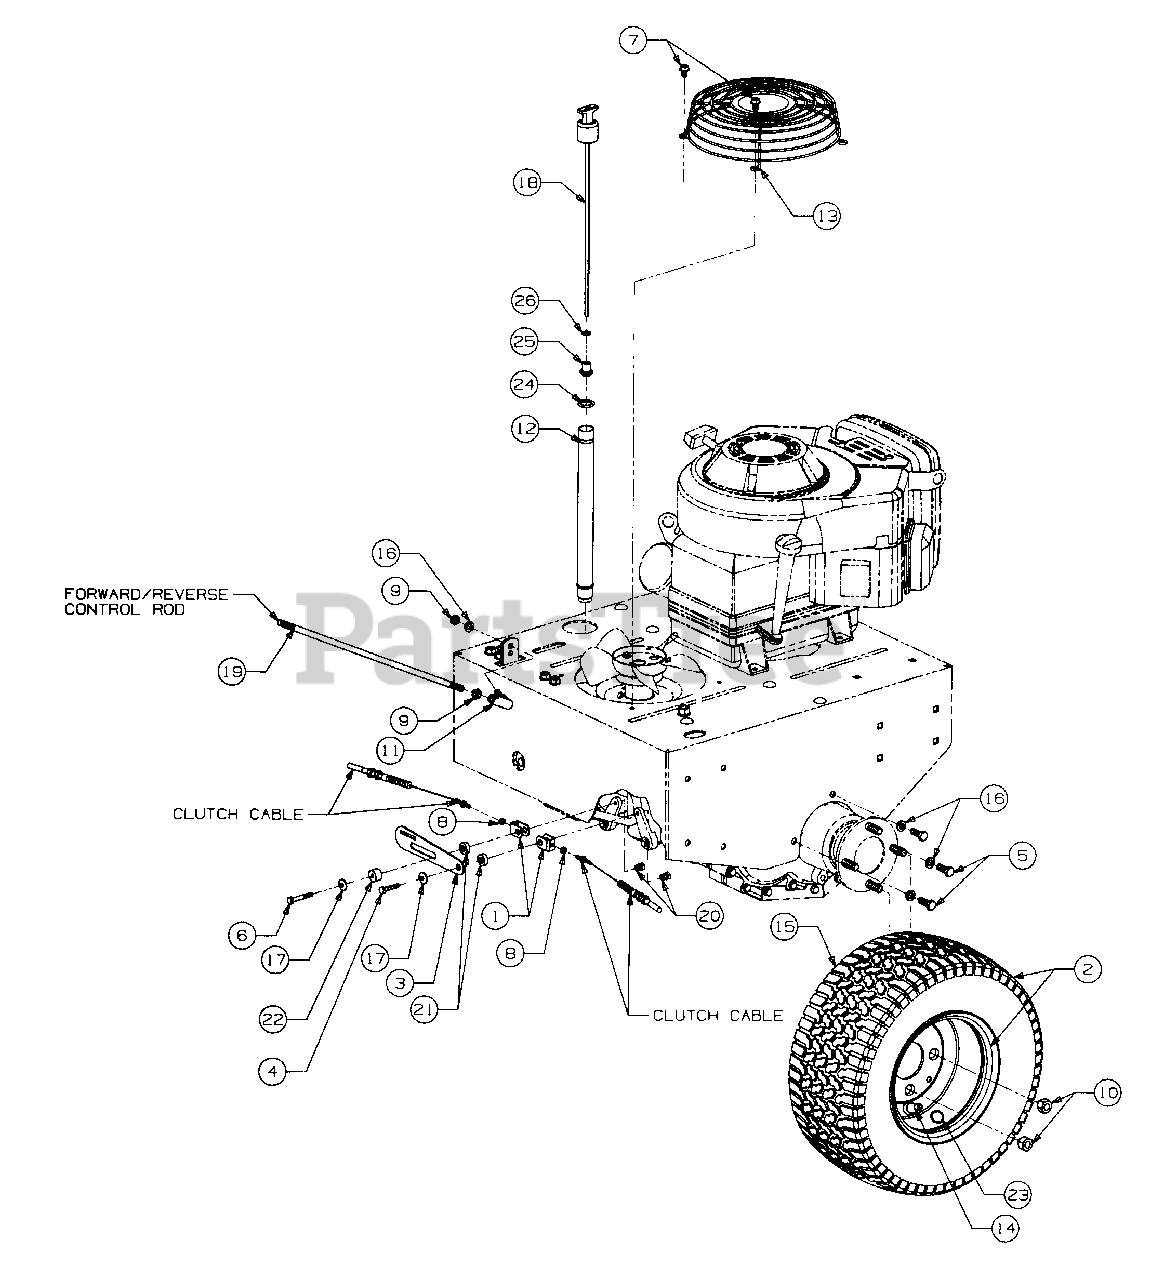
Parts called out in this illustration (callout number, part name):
1	U-Clevis, Clutch Cable
2	Wheel & Tire Assy, Complete, 16 X 7.5-8 (Includes Ref No. 23)
3	Plate, Parking Brake Switch Mount
4	Screw, Hex Cap, 1/4-28 X 1.25 Lg GR5
5	Screw, Hex Cap, 3/8-16 X 1.04 GR5
6	Screw, Hex Cap, 1/4-28 X 1.75 Lg GR5
7	Screw, Hex Wash Hd Tapp, 5/16-18 X .50 Lg
8	Nut, Hex Jam, #10-32
9	Nut, Hex Jam, 3/8-24 GR5
10	Nut, Lug, 1/2-20
11	Ball Joint, 3/8-24
12	Tube, Oil Fill
13	Guard, Fan Cover
14	Valve, Tubeless Air
15	Tire, Turf Chief, 16 X 7.5-8
16	Washer, Lock, 3/8
17	Washer, Bell, .265 X .75 X .062 Thk
19	Rod, F/RControl
20	Nut, Clevis Spacer, 1/4-28
21	Spacer, Clevis
22	Spacer, Switch Engagement
23	Label, Inflation
25	Seal, Rubber
26	Washer, Plain, 5/16
